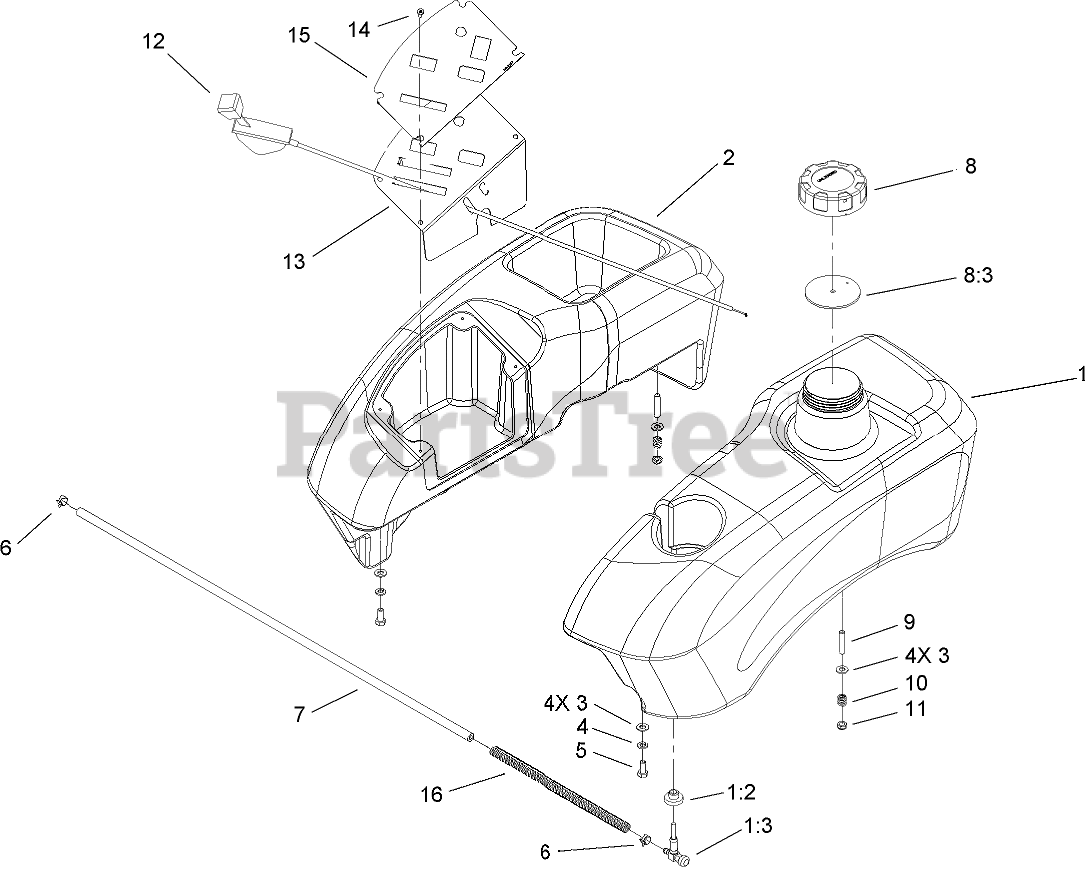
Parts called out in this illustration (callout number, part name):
1	Fuel Tank ASM
1:2	BUSHING
1:3	VALVE-FUEL
2	Tank-Console
3	WASHER-PLAIN
4	WASHER-LOCK
5	SCREW-HH
6	CLAMP-HOSE
7	HOSE-FUEL
8	GAS CAP ASM
8:3	GASKET-CAP, GAS
10	SPRING-TANK, FUEL
11	NUT-LOCK, NI
12	CABLE-THROTTLE
13	PANEL-CONTROL
14	SCREW-PPH
15	DECAL-PANEL, CONTROL
16	COVER-CONDUIT
